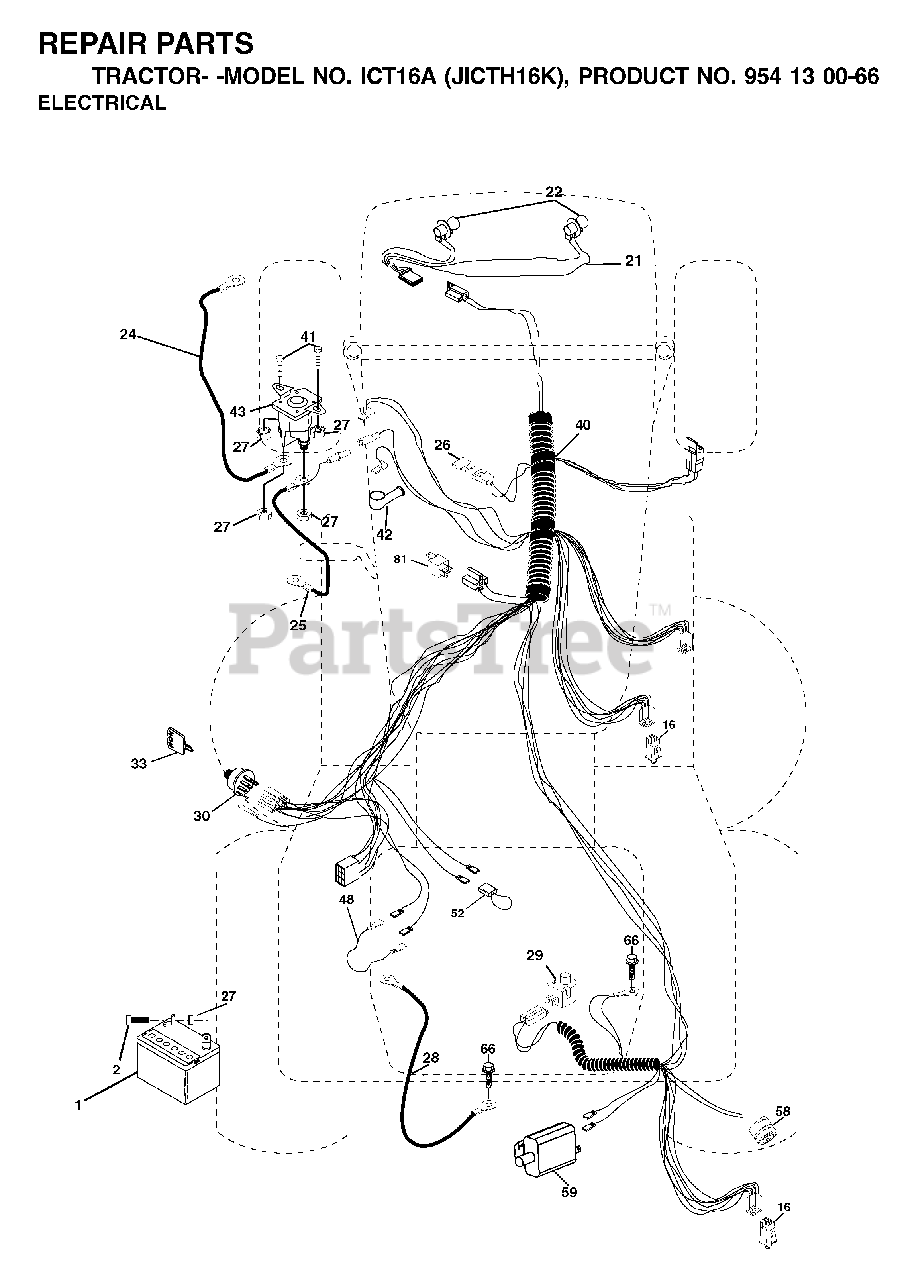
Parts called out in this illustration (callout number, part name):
1	REPL BY 532 12 38-99
16	SWITCH INTERLOOK PUSH-IN
21	HARNESS.W/LIGHT SOCKET
22	LIGHTBULB
24	BATTERY CABLE GT
25	CABLE BATTERY
26	FUSE 20AMP
27	NUT
28	CABLE GROUND
29	PLUNGER SWITCH (COLOR:OLIVE)
30	IGNITION SWITCH
33	KEY MLD GEN DELTA
42	TERMINAL COVER
43	SOLENOID
52	WIRE PROTECTION LOOP
58	BUZZER
81	RELAY.ASSY.T
